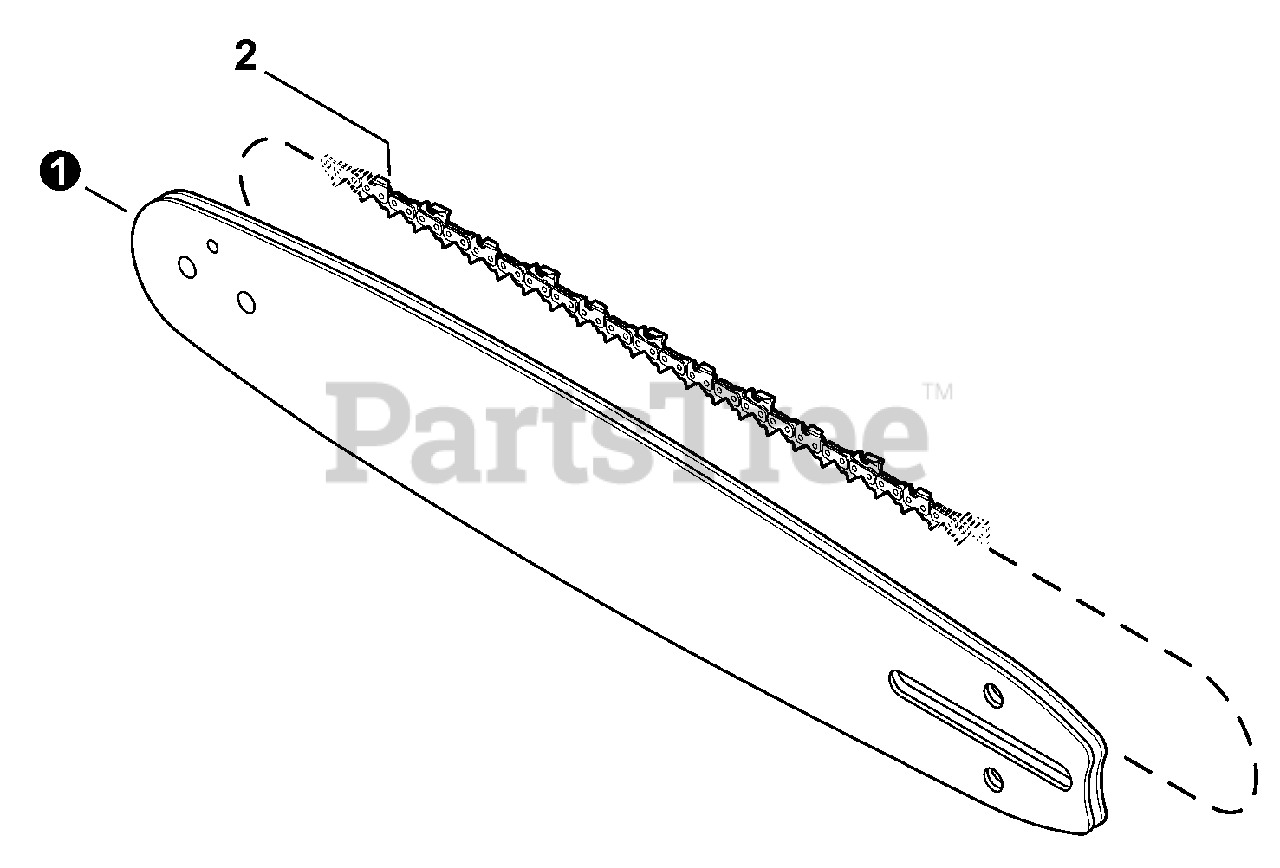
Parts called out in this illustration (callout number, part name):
1	BARRA DE GUÍA 45cm
1	BARRA DE GUÍA 50cm
1	BARRA DE GUÍA 60cm
1	GUIDE BAR, 20" ARMOR TIP
1	GUIDE BAR, 24" ARMOR TIP
1	GUIDE BAR, 28" ARMOR TIP
2	CADENA DE SIERRA - 18" (45cm)
2	CADENA DE SIERRA - 20" (50cm)
2	CADENA DE SIERRA - 24" (60cm)
2	CADENA DE SIERRA - 28" (70cm)
